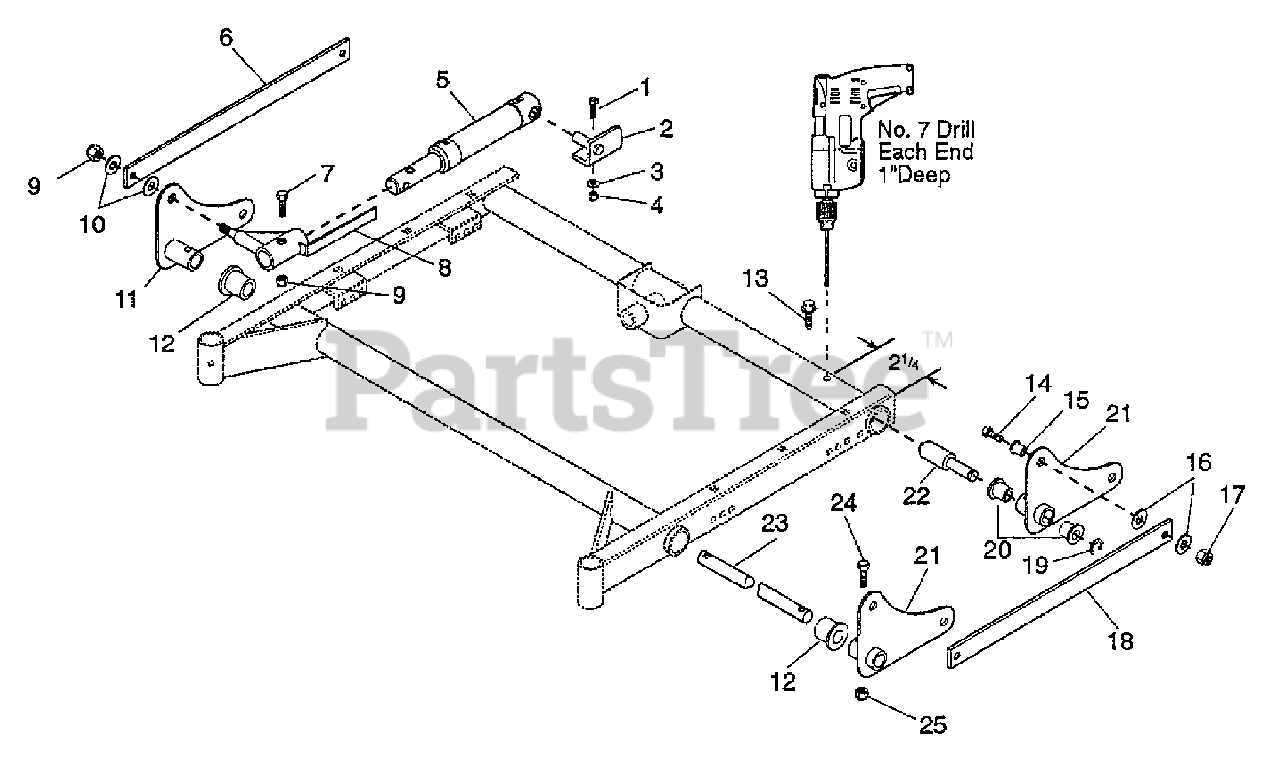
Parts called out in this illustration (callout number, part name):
1	Bolt-Hex .38-16 x 1.50 Grade 5
2	Deck Lift Rear Deck
3	Washer-Flat-Steel .438 x 1.0 x .083
4	Nut-Locking-Nylon .375-16 Grade 2
5	Cylinder, Hydraulic
6	Link Bar, Right Hand, Deck Lift
7	Bolt-Hex .50-13 x 2.00 Grade 5
8	Lift Ram Terminal Pin
9	Nut-Locking-Nylon .50-13 Grade 5
10	Washer-Flat-Steel .563x1.375x.109
11	Lift Arm Weldment
12	Bushing-Flange 1.020 x 1.385 x .75 x 1.75
13	Screw-Tapping 250-20 x.50
14	Bolt-Hex .31-18 x 1.25 Grade 5
15	Bushing-Flange .325 x .500 x .513 x .875
16	Washer-Flat-Steel .38 x .875 x .083
17	Nut-Locking-Nylon .312-18 Grade 2
18	Link Bar-Deck Lift
19	Ring-Retaining-External .750 x .050
20	Bushing-Flange .762 x 1.0 x .580 x 1.48
21	Lift Arm Weldment, Left Hand
22	Stub Shaft, 50" Lift
23	X-Shaft 50" Deck Lift
24	Bolt-Hex .31-18 x 1.75 Grade 5
25	Nut-Locking-Nylon .312-18 Grade 2
